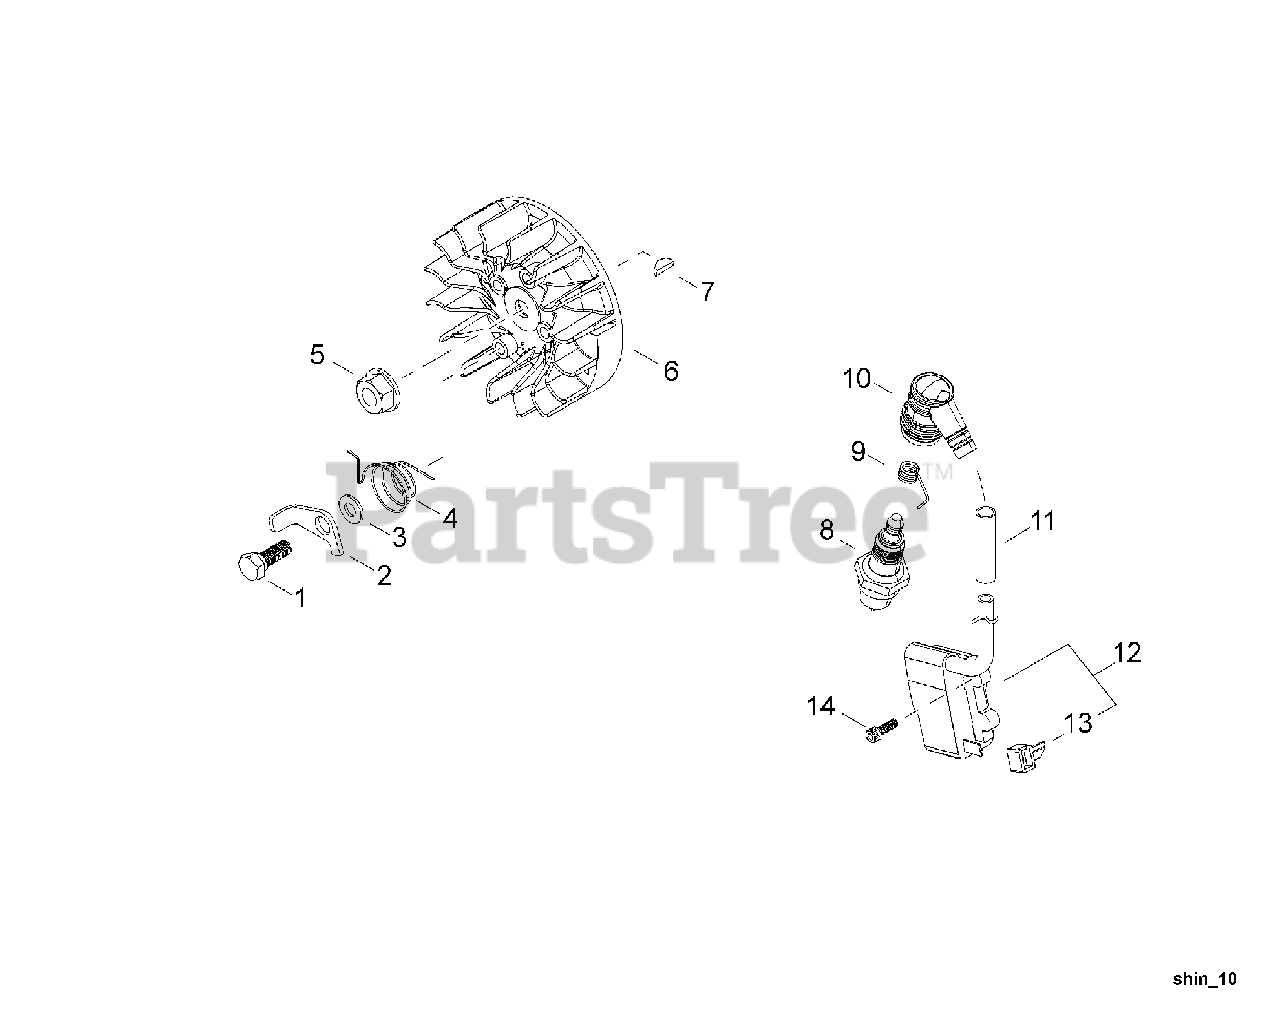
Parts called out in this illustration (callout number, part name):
1	BOLT 6
2	PAWL
3	WASHER 6
4	SPRING, TORSION
5	NUT M8×1.0
6	FLYWHEEL
7	KEY, WOODRUFF 3×10
8	SPARK PLUG - RCJ6Y
9	TERMINAL, SPARK PLUG
10	CAP, SPARK PLUG
11	TUBE, IGNITION COIL
12	COIL ASSY, IGNITION
13	COVER, TERMINAL
14	BOLT, ADHESIVE M4×20
